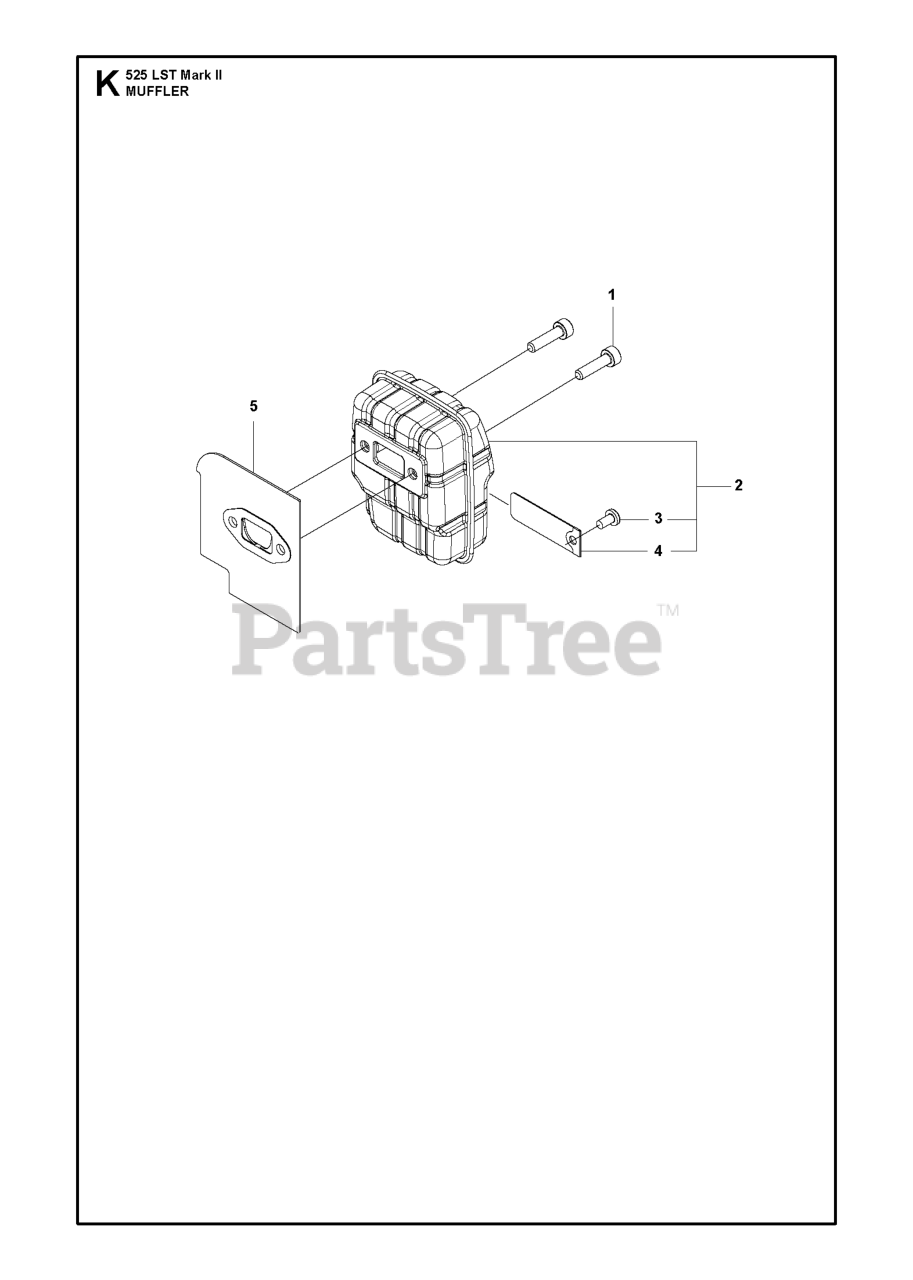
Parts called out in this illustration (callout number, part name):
1	BOLT
3	SCREW CRPANT TYPE F ST4.2X9.5
4	SPARK ARRESTER
5	GASKET MUFFLER
